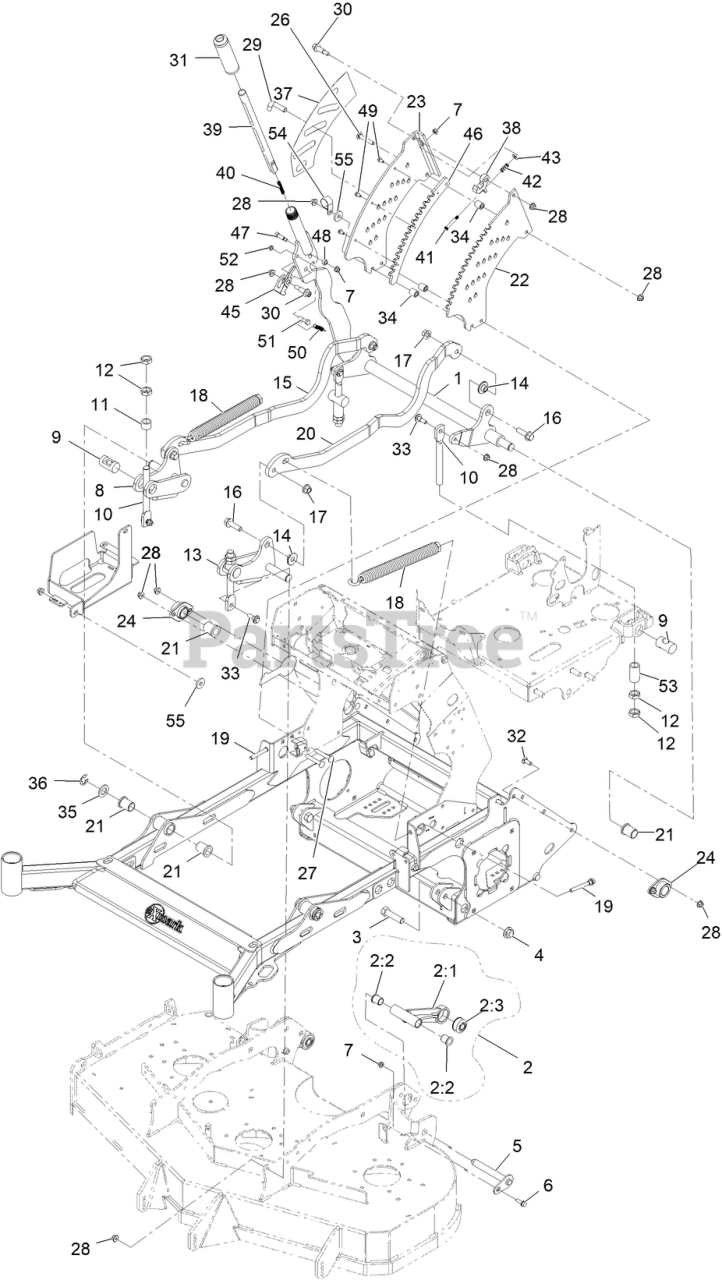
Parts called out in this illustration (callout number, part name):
1	CROSS SHAFT-DECKLIFT-REAR [BLACK]
2	ASM-DECK STRUT W/BUSHINGS
2:1	ASM-Deck Strut
2:2	BUSHING-IGUS FLNG .75X1
2:3	Bushing
3	SCREW-HH
4	NUT-FLNG 5/8-18 CTRLOCK GR G
5	ASM-DECK STRUT PIN
6	SCREW-HHF
7	NUT-HF, NI
8	Weld-Arm-Decklift-Front-RH
9	TRUNION-DECK LIFT
10	LINK-DECKLIFT
11	SPACER-DECKLIFT
12	NUT-JAM
13	Weld-Arm-Decklift-Front-LH
15	LINK-DECKLIFT-RH
16	SCREW-HHF
17	Nut-Lock 1/2-13
18	SPRING-EXTENSION
19	BOLT-SHOULDER
20	LINK-DECKLIFT-LH
21	BUSHING-FLANGED
22	Plate-Inner-HOC
23	Plate-Outer-HOC
24	SUPPORT-HOC SHAFT
26	BOLT-CARR, SHORT NECK
27	SCREW-CARR
28	NUT-HF, NI
29	PIN-HOC
30	BOLT-SHOULDER
31	GRIP-HANDLE-DECKLIFT
32	SCREW-CARR
33	SCREW-SHOULDER, HHF
34	SPACER-HOC
36	RING-RETAINING, EXT
37	DECAL-HEIGHT OF CUT
38	PAWL-DECKLIFT
39	PLUNGER-TOP
40	SPRING-COMPRESSION
41	SCREW-SHOULDER-CAP
42	SPRING-COMPRESSION
45	Pawl-Lock-Decklift
46	Plate-Doubler-HOC-Lock
47	BOLT-SHOULDER
49	SCREW-HWH
50	SPRING-EXTENSION
51	BOLT-SHOULDER
52	NUT-LOCK, NI
53	SPACER 1.13 O.D. X .81 I.D. X 2.05L
54	R-Clamp
